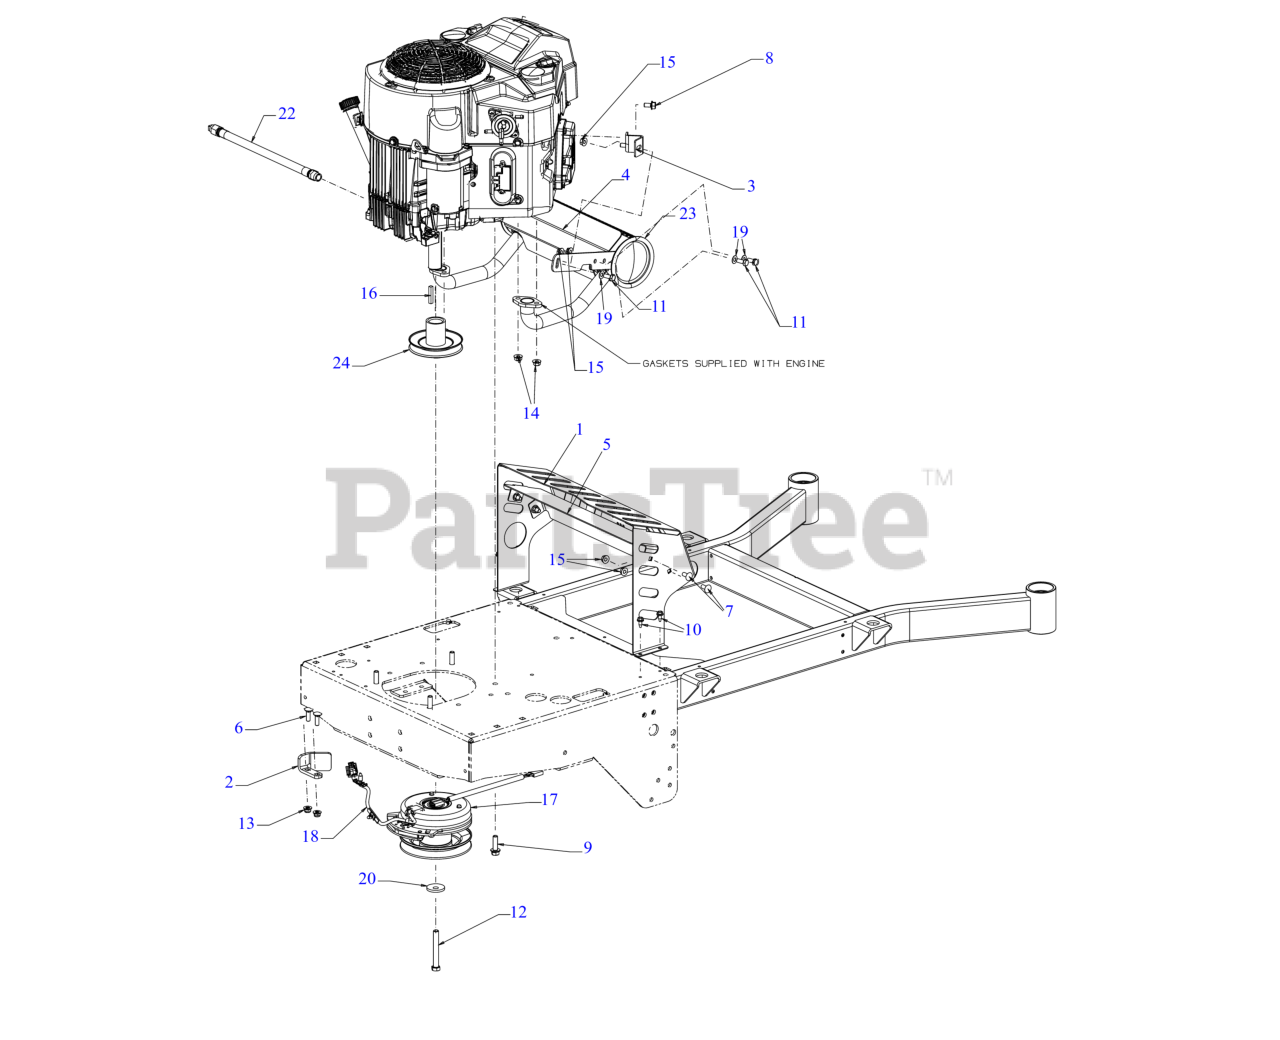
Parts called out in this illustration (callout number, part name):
1	MUFFLER COVER
2	PTO CLUTCH RETAINER BRACKET
3	MUFFLER MOUNTING BRACKET
4	MUFFLER SHIELD
5	INNER MUFFLER SHIELD
6	CARRIAGE BOLT 5/16-18 x 1.00
7	CARRIAGE BOLT 5/16-18 x .75
8	SCREW M8 x 1.25 x 16MM GR8.8
9	SCREW 3/8-16 x 1.25 GR5
10	SCREW 1/4-20X.625
11	SCREW 5/16-18 x .75 GR5
12	SCREW 7/16-20 x 3.25 GR5
13	FLANGE LOCK NUT 5/16-18
14	HEX FLANGE NUT
15	HEX FLANGE NUT
16	SQUARE KEY 1/4 x 1.50
17	PTO CLUTCH
18	CLUTCH HARNESS 11"
19	FLAT WASHER
20	FLAT WASHER .45 x 1.5 x .172 HT
22	OIL DRAIN HOSE
23	MUFFLER (ROUND)
24	ENGINE PULLEY (1.125")
